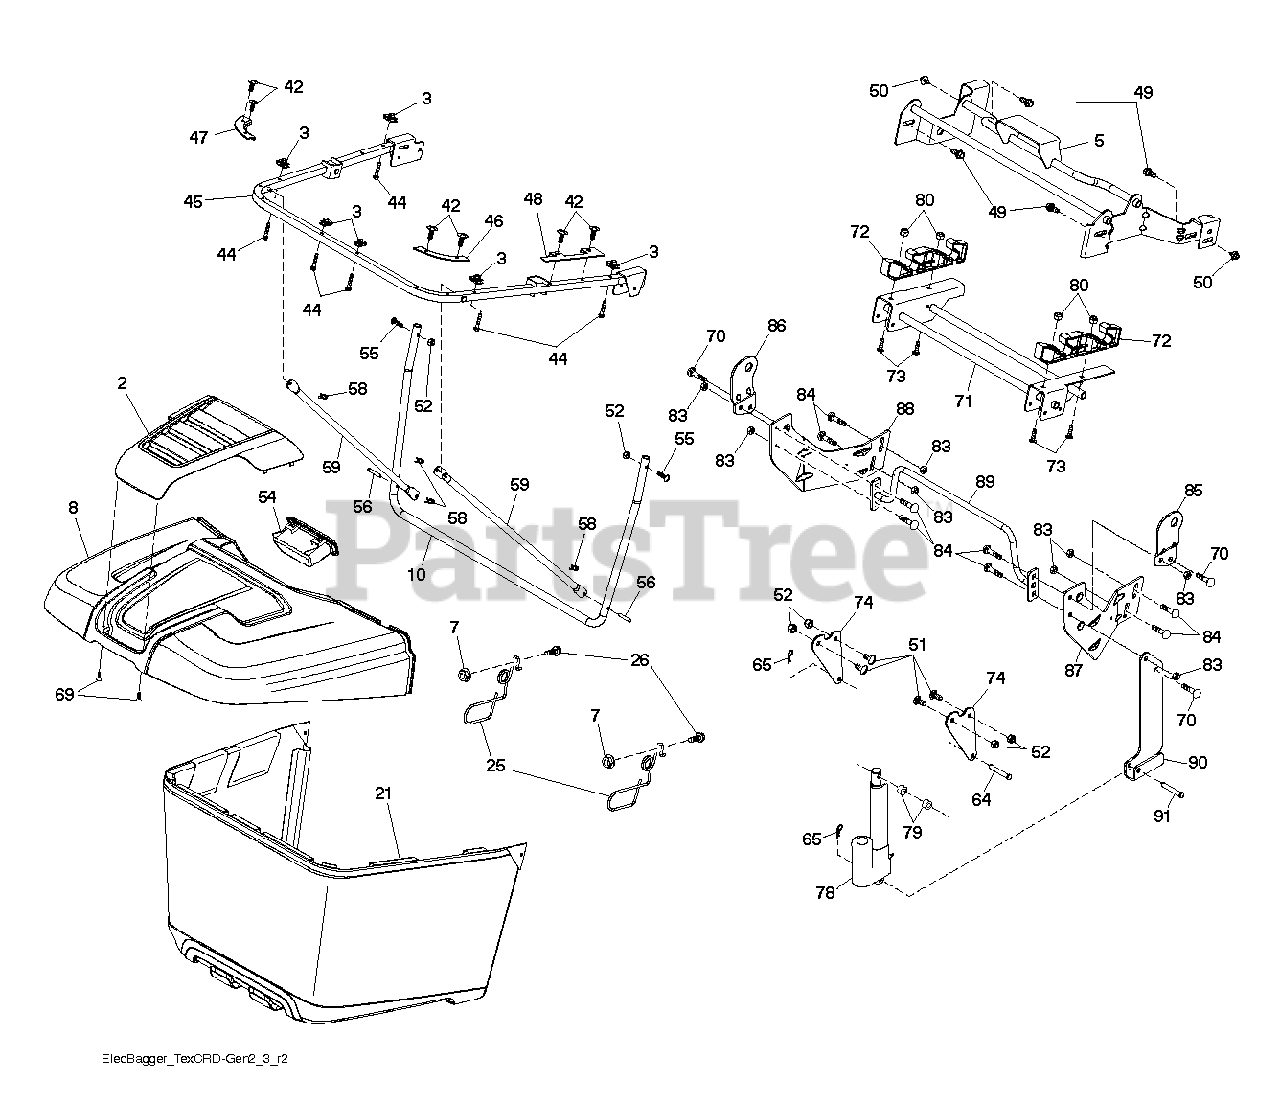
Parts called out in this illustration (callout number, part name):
2	APPLIQUE.BAGGER
3	1/4-20 U NUT
7	NUT T
10	FRAME TEX_CRD_GEN2 BAGGER FRAM
21	BAG FRAME BAGGER ASSEMBLY. HUS
25	LATCH LATCH. BAG. CRD GEN 2
26	SCREW HEX CRT
42	CLIP CHRISTMAS TREE CLIP
45	FRAME TEX_CRD_GEN2 UPPER U FRA
46	CONNECTOR RIGHT BAGGER CORNER
47	CONNECTOR LEFT BAGGER CORNER C
48	BAFFLE BAGGER SIDE CLOSE-OUT
49	BOLT, SHOULDER 5/16-18
50	BOLT, 5/16-18 X 1 3/4
51	BOLT.CARR.SQNK.5/16-18UNC.X3/4
52	NUT.71038.31-18.HEX.NYLOCK
54	HANDLE BAGGER TOP FRONT HANDLE
55	BOLT
56	PIN.CLEVIS.183
58	RETAINER CLIP PM
59	TUBE BAGGER SPREADER TUBE, TEX
65	RETAINER M
69	SCREW,#8.FLAT.HEAD.DRILL.TIP
70	SCREW, 3/8-16X3/4
73	BOLT.CARRIAGE.5/16-18
79	SPACER.NYLON.75" X .4375
80	NUT LOCK HEX FLANGE 5/16-18
83	NUT
84	BOLT D
85	BRACKET.RH.PIVOT.ELE.DUMPX431
86	BRACKET.LH.PIVOT.ELE.DUMPX431
87	BRACKET.RH.MID.SUP.BAG.TEX.CRD
88	BRACKET.LH.MID.SUP.BAG.TEX.CRD
89	WELDMENT.OFFSET.STRUT.SUP.BLAC
90	BRACKET.ELE.DUMP.ACT.BAG.X431
91	PIN.CLEVIS.(.375 X 1.25)
